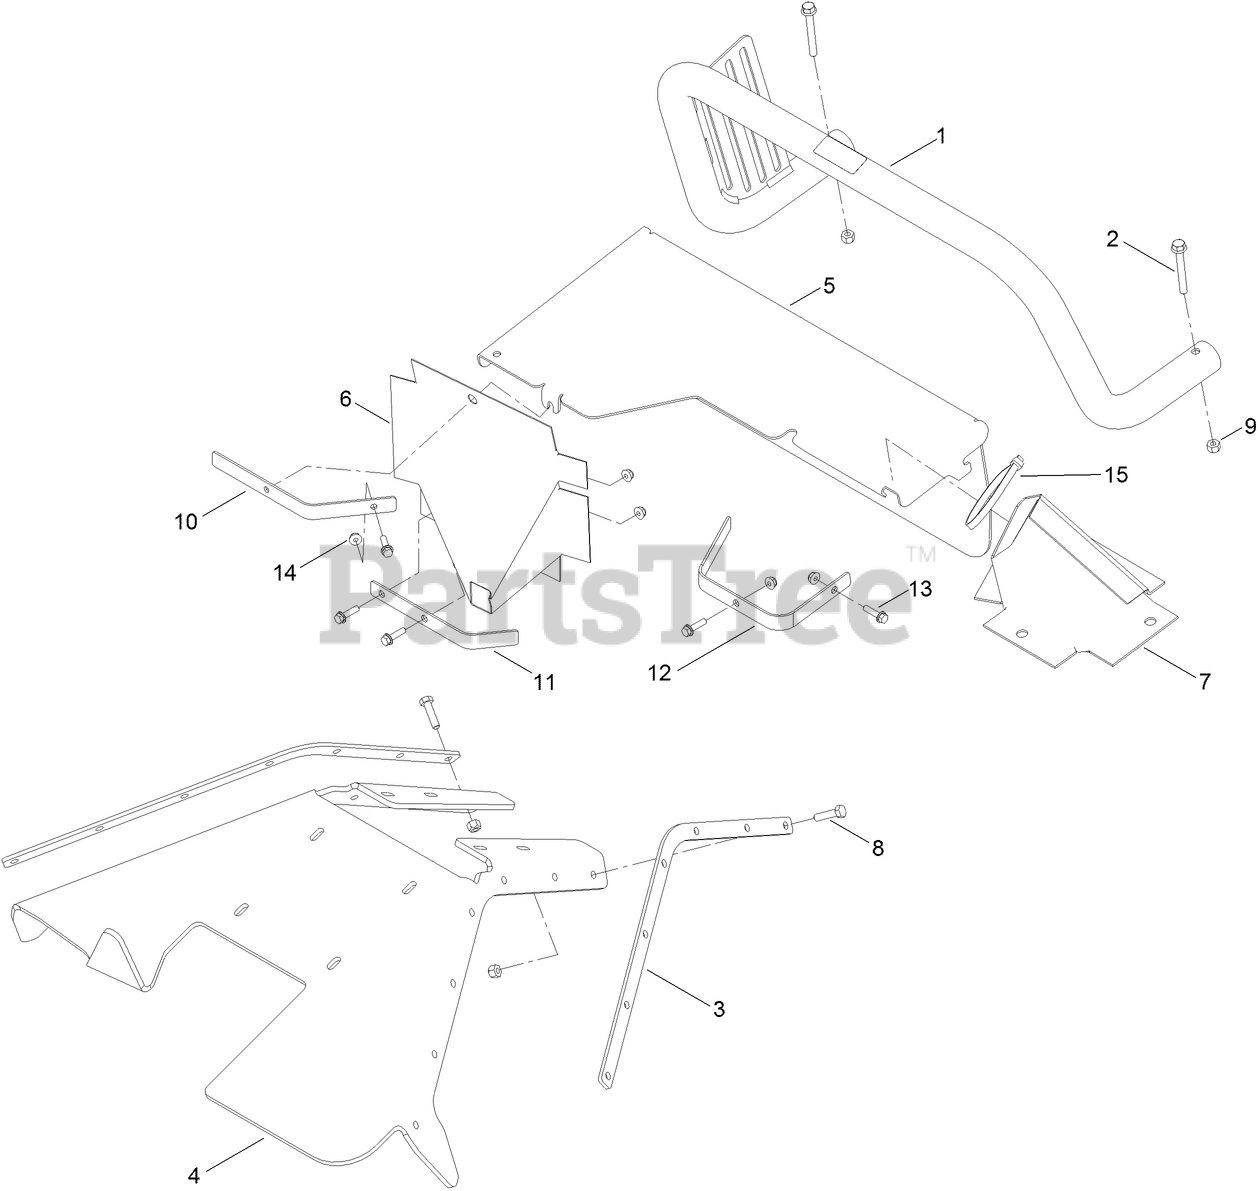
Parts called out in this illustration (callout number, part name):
1	MUFFLER GUARD DECAL ASM
2	SCREW-HHF
3	PLATE-CLAMP,CHIP
4	PLATE-MOUNT,GUARD
5	COVER, HYDRAULIC
6	COVER, CANVAS CYLINDER
7	COVER, CANVAS HYD HOSES
8	SCREW-HH
9	NUT-LOCK, NI
10	BRACKET-FRAME, TOP
11	BRACKET-FRAME, BOTTOM
12	BRACKET-BOOT
13	SCREW-HHF
14	NUT-HF
15	TIE-CABLE
